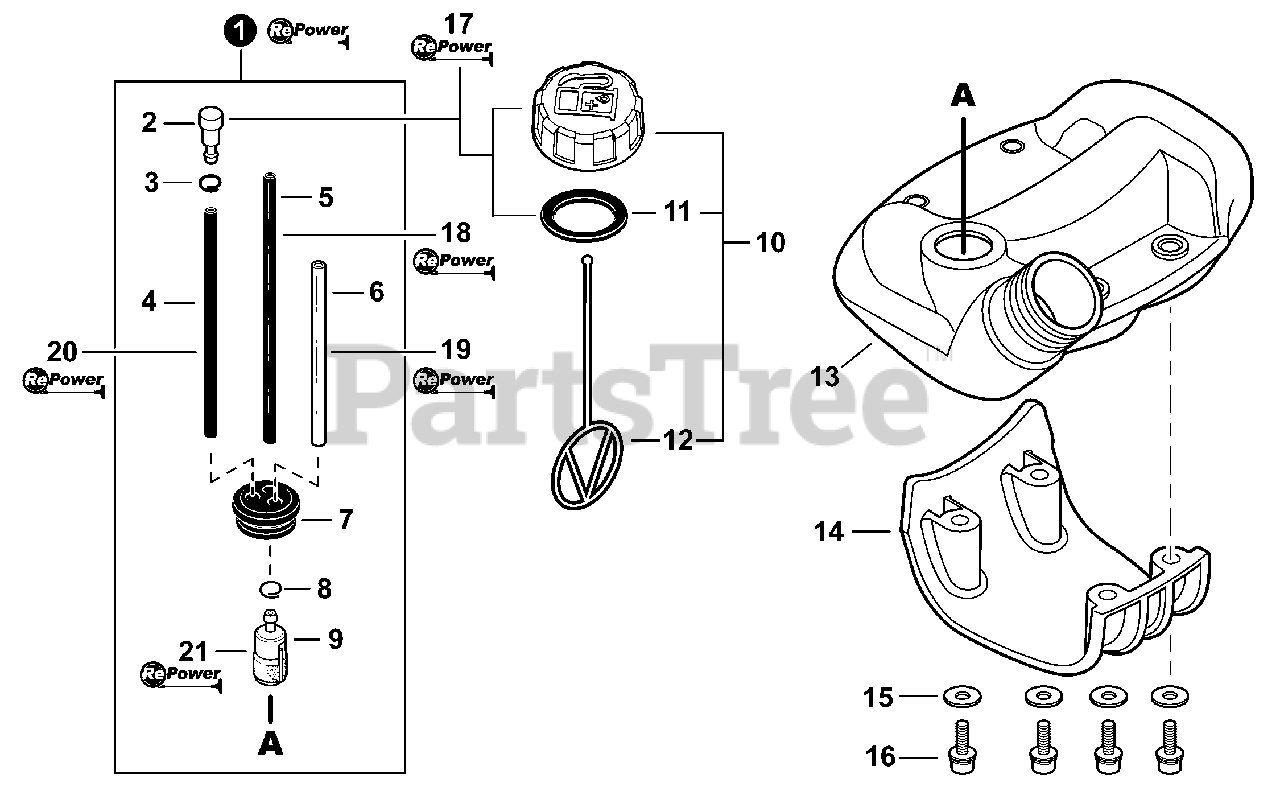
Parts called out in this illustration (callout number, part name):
1	FUEL SYSTEM KIT
2	VENT ASSY
3	CLIP Ø6.5 MM
4	PIPE, FUEL 3×6×35 BLACK
5	PIPE, FUEL 3×5×195 BLACK
6	PIPE, FUEL 3×6×75 CLEAR
7	GROMMET, FUEL
8	CLIP Ø6
9	FILTER, FUEL 125-528
10	CAP ASSY, FUEL
11	GASKET, FUEL CAP
12	CONNECTOR, CAP L= 100 MM
13	TANK, FUEL
14	GUARD, FUEL TANK
15	WASHER 5.5×12×0.8
16	BOLT 5×25
17	CAP/VENT KIT - REPOWER
18	BULK PIPE - 3×5 MM BLACK (4 PIECES×2 M)
19	BULK PIPE - 3×6 MM CLEAR (4 PIECES×2 M)
20	BULK PIPE - 3×6 MM BLACK (4 PIECES×2 M)
21	TUNE-UP KIT - REPOWER
